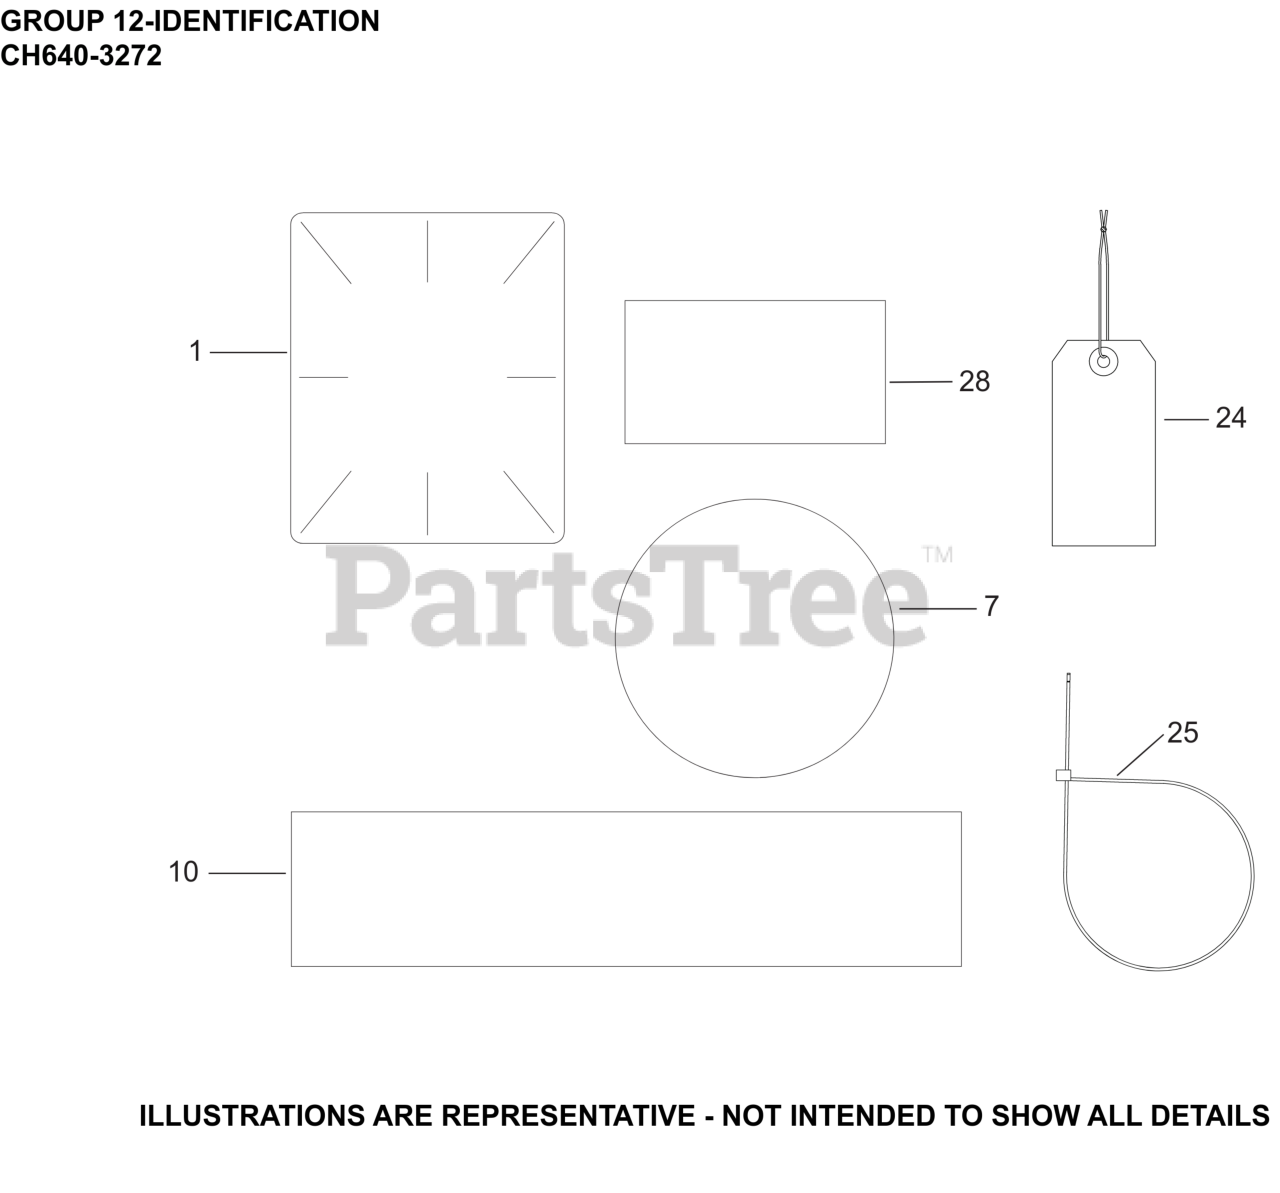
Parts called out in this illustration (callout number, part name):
1	LABEL, CLEAR LAMINATION
7	LABEL, GRASS SCREEN
10	DECAL, STOPPING INSTRUCTION
24	TAG, HANG (OIL SENTRY)
28	DECAL, USA
NI	LABEL, LPAC (ENGINE HP)
